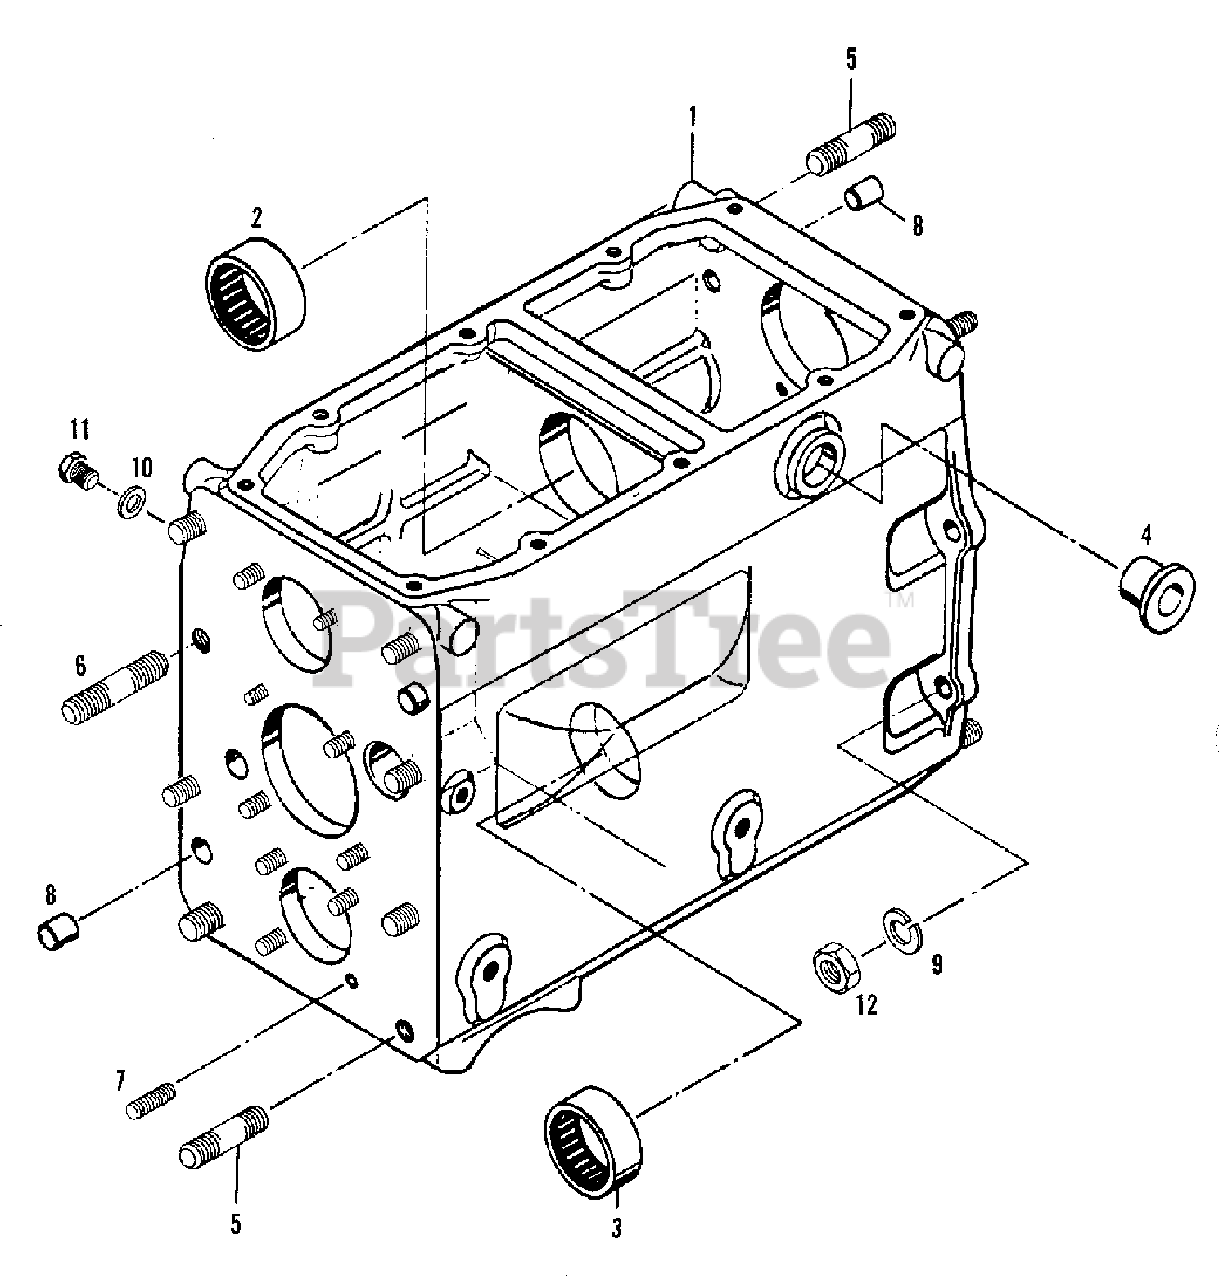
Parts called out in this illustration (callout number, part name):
1	HOUSING ASSEMBLY, transmission (Incl. Items 2 thru 8)
2	BEARING, shell type needle
3	BEARING, shell type needle
4	GUIDE, shift lever
5	STUD, M12 x 28 (Seal lock No. 10)
6	STUD, M12 x 48 (Seal lock No. 10)
7	STUD, M8 x 18 (Seal lock No. 10)
8	PIN, dowel
9	LOCKWASHER, M12
10	WASHER, seal
11	SCREW, lock, (For oil gauge)
